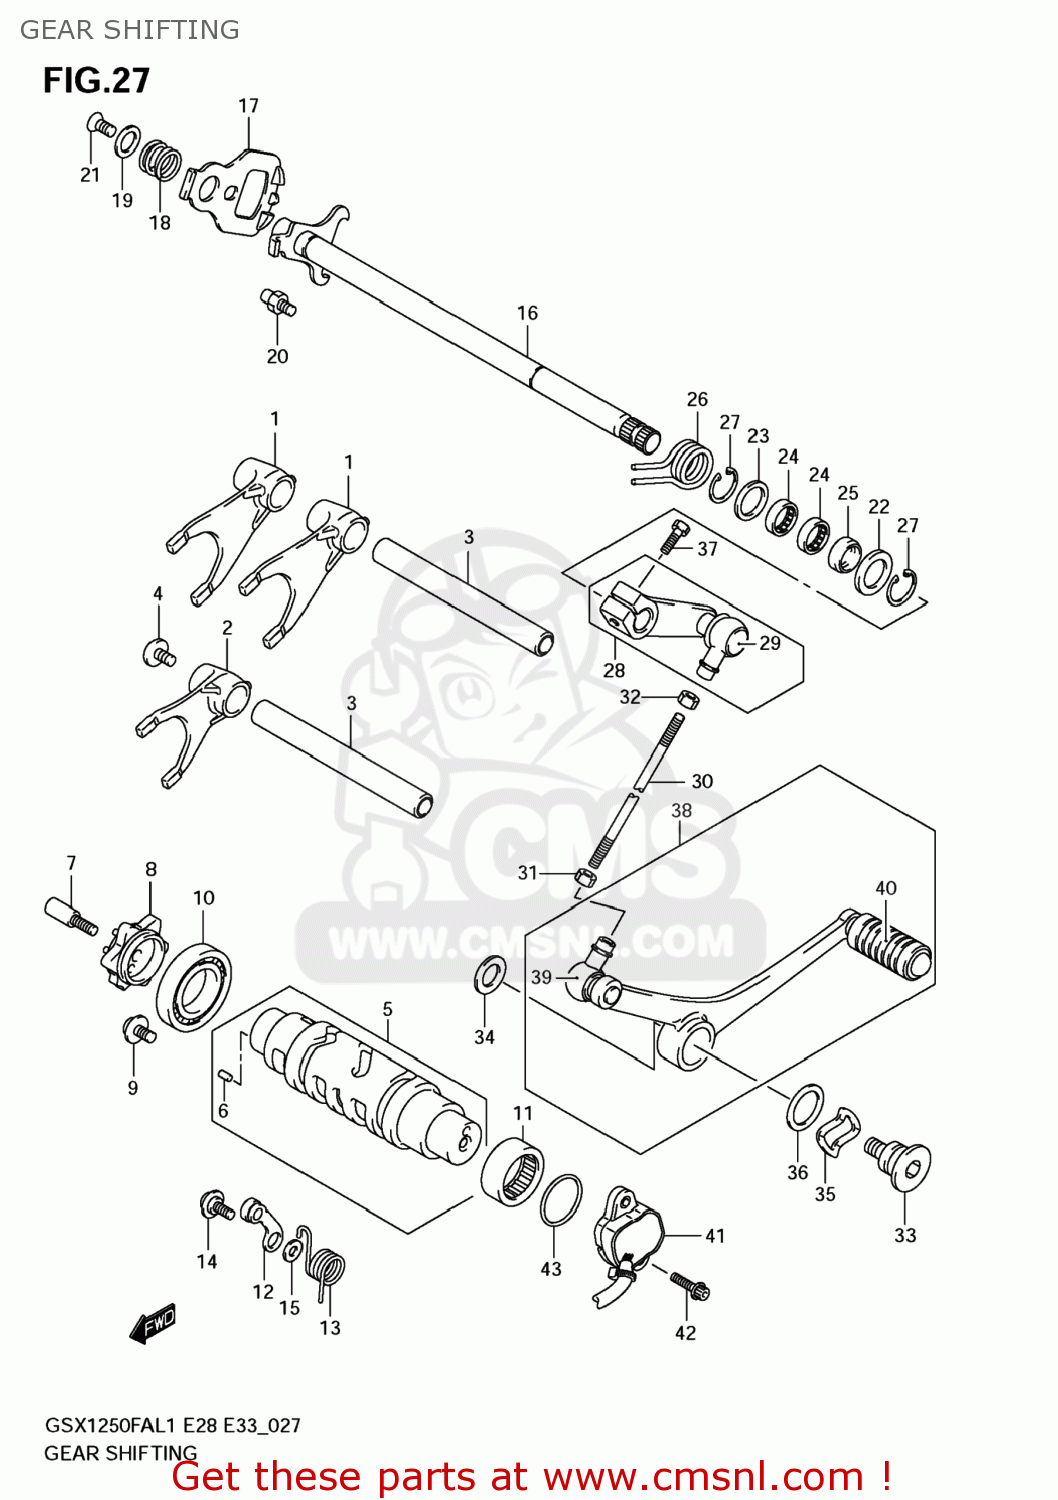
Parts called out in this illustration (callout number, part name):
1	FORK,GEAR SHIFT NO.1
2	FORK,GEAR SHIFT NO.3
3	SHAFT,GEAR SHIFT FORK(L:128)
4	SCREW(6X12)
5	CAM,GEAR SHIFT
6	PIN
7	BOLT,GEAR SHIFT CAM PLATE
8	PLATE,GEAR SHIFT CAM
9	SCREW(6X12)
10	BEARING(25X47X8)
11	BEARING(25X32X12)
12	STOPPER,SHIFT CAM
13	SPRING,GEAR SHIFT CAM STOPPER
14	BOLT(6X14.3)
15	WASHER
16	SHAFT,GEAR SHIFT
17	PLATE,GEAR SHIFT CAM DRIVE
18	SPRING,GEAR SHIFT PLATE RETURN
19	WASHER,GEAR SHIFT SHAFT END
20	STOPPER,GEAR SHIFT ARM
21	SCREW(6X16)
22	WASHER(14X29X0.8)
23	SHIM(14X24X1)
24	BEARING(14X20X12)
25	SEAL,OIL(14X22X7.3)
26	SPRING
27	CIRCLIP
28	ARM,GEAR SHIFT LINK
29	COVER,DUST
30	ROD,GEAR SHIFT LINK
31	NUT
32	NUT
33	BOLT,GEAR SHIFT LEVER
34	WASHER(10X28X2.3)
35	WASHER
36	SHIM(18X26X0.8)
37	BOLT
38	LEVER ASSY,GEAR SHIFT
39	COVER,DUST
40	RUBBER,GEAR SHIFT PEDAL
41	SENSOR ASSY,GE
42	BOLT(5X16)
43	O RING(D:2.4,ID:26.2)
